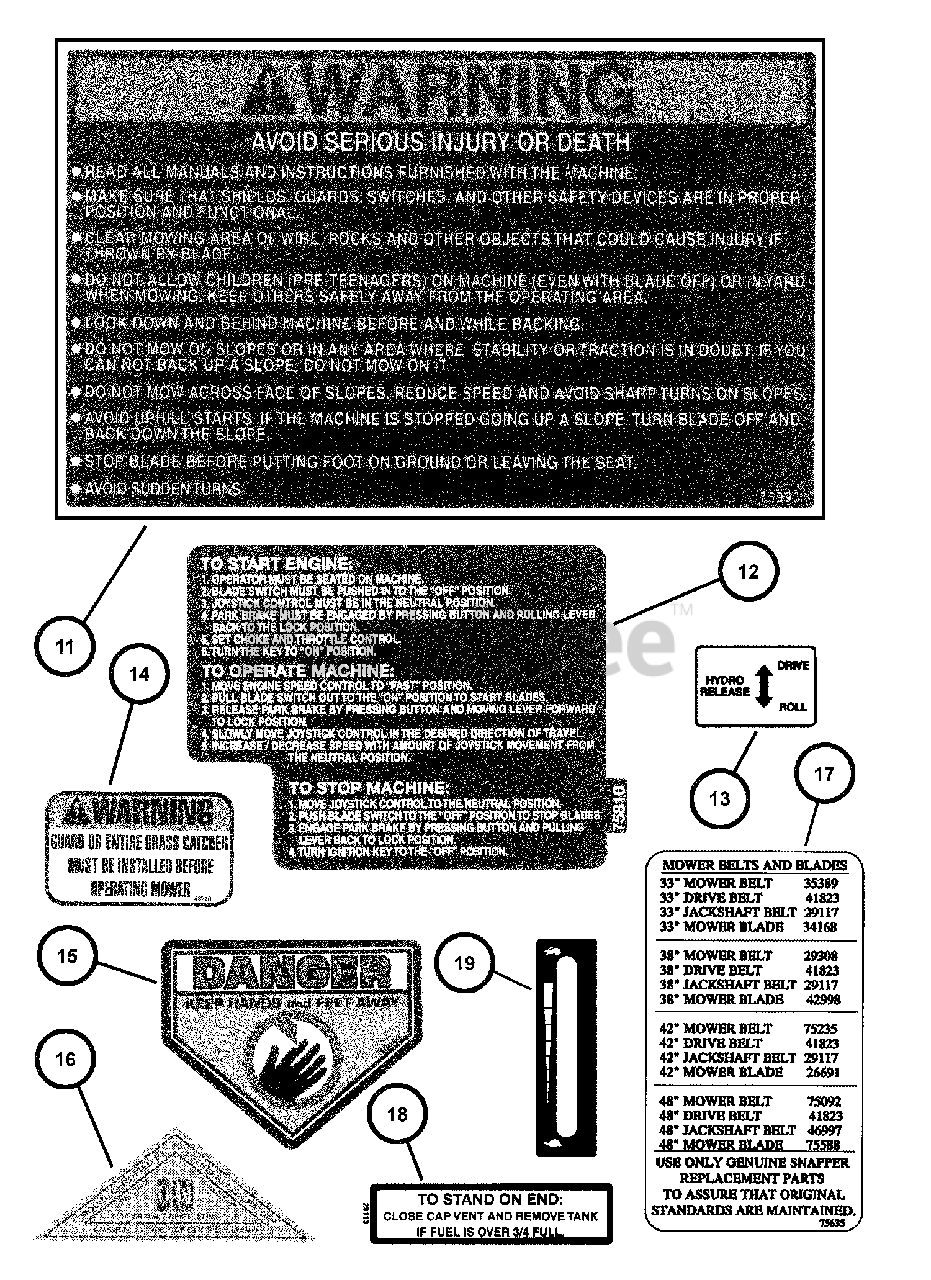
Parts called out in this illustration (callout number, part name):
11	DECAL, Warning, Read Manuals & Instructions
12	DECAL, Operating Instructions
13	DECAL, Hydro Release
14	DECAL, Chute/Deflector
15	DECAL, Danger, Cut Finger (CPSC)
16	DECAL OPEI Ride-On
17	DECAL, Service Parts, HOZ Domestic
18	DECAL, Caution, Fuel (English)
19	DECAL, Throttle/Choke Control
